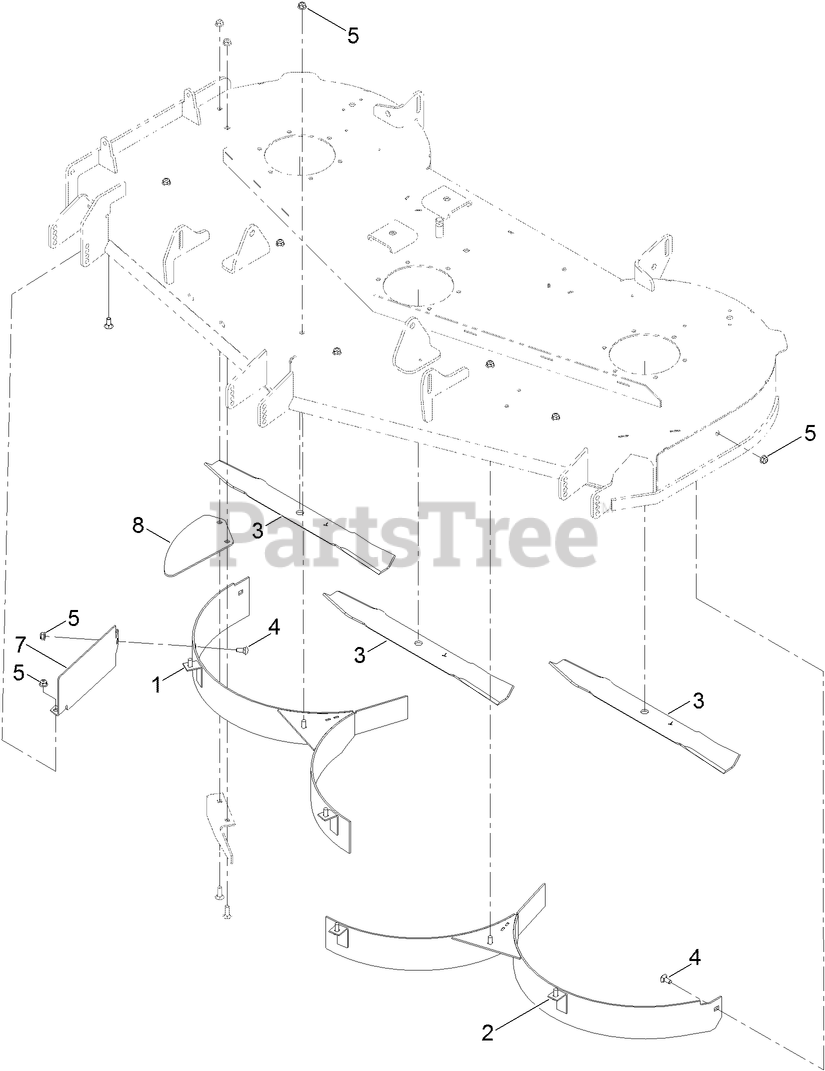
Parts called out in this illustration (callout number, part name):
1	BAFFLE-MULCH, RH
2	BAFFLE-MULCH, LH
3	BLADE-MULCH, 20.50 INCH
4	BOLT-CARR
5	NUT-HF, NI
7	GUARD-BAFFLE
8	PLATE-FILLER
